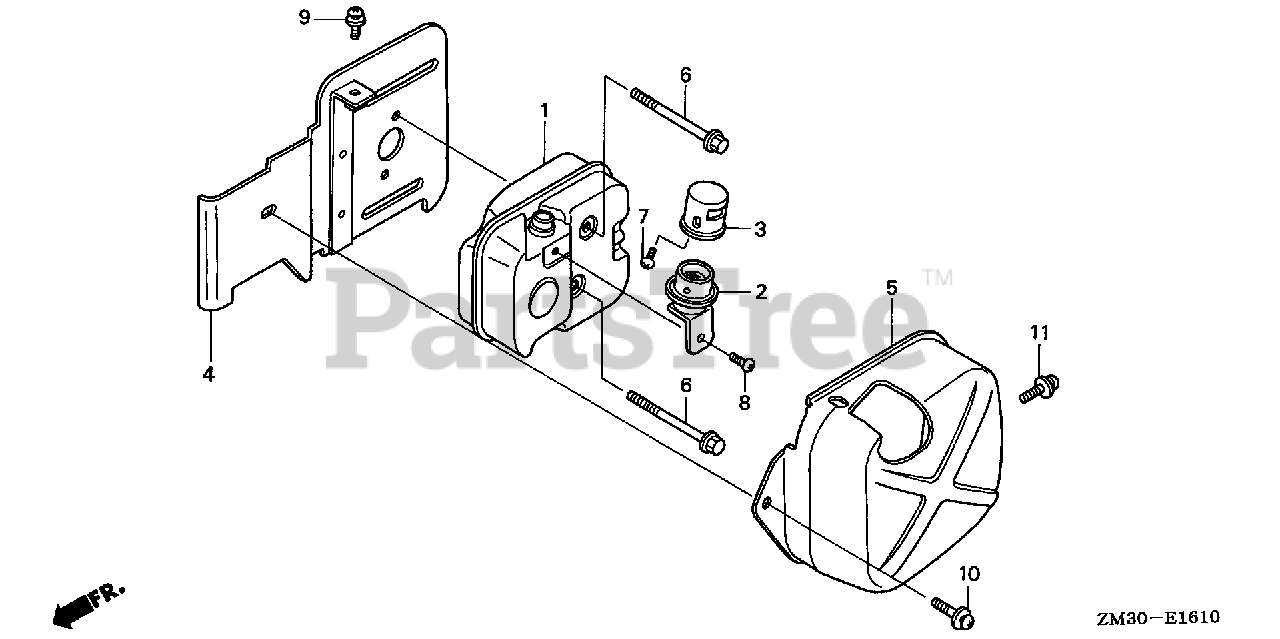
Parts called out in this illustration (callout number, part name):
2	ARRESTER, SPARK
4	GUIDE, AIR EX.
5	INNER COVER, TOP
6	BOLT, FLANGE (5X50)
7	SCREW, TAPPING (4X6)
8	SCREW-WASHER (4X6)
9	SCREW-WASHER (5X8)
10	SCREW-WASHER (5X10)
11	SCREW-WASHER (5X16)
